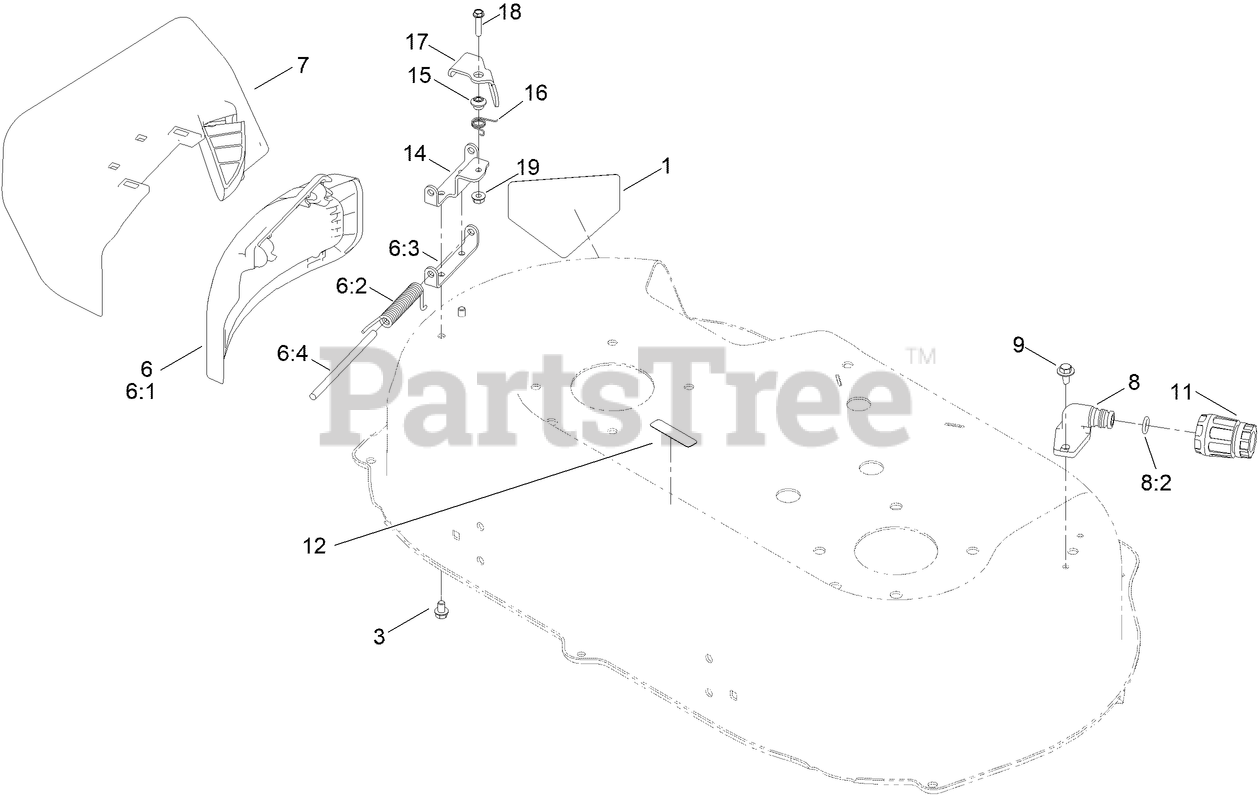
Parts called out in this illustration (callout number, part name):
1	DECAL-DANGER
6	SIDE DEFLECTOR SERVICE ASM
6:1	DEFLECTOR-DISCHARGE, SIDE
6:2	SPRING-TORSION, COVER
6:3	BRACKET-LOCKOUT
7	SIDE DISCHARGE CHUTE ASM
8	FITTING-WASHOUT
8:2	O-RING
9	SCREW-HWH, THD ROLL
11	CONNECTOR-HOSE
12	DECAL-WARNING
14	BRACKET-LOCKOUT
15	SPACER
16	SPRING-TORSION
17	LEVER-LOCKOUT
18	SCREW-HWH
19	NUT-HEX FLANGE
